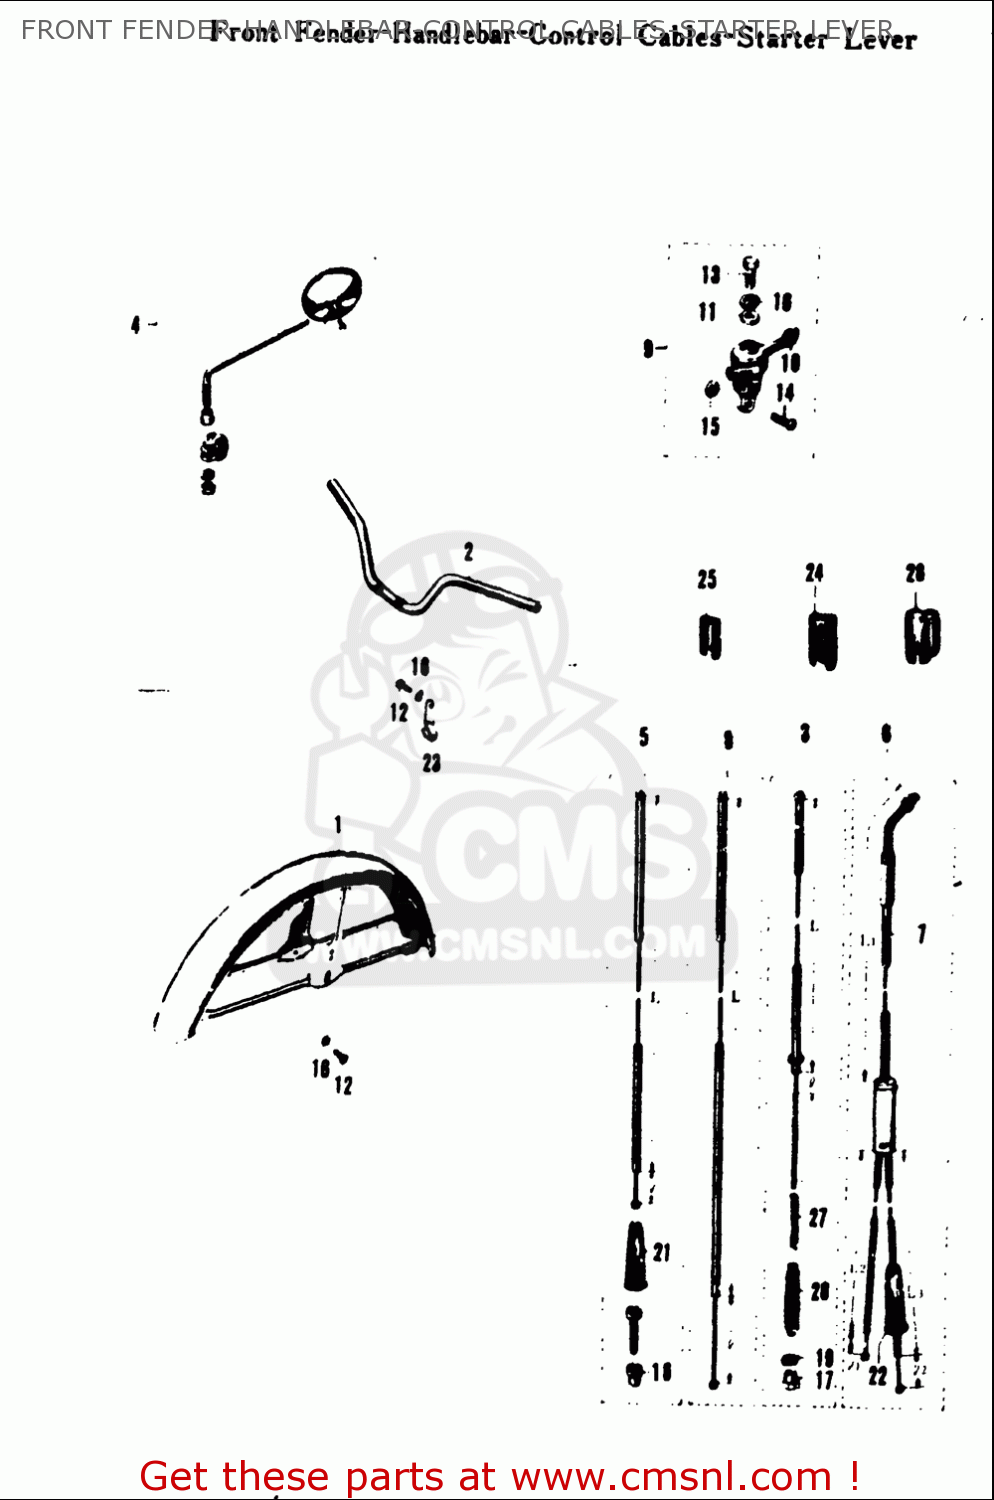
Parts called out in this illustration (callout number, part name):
5	WIRE,CLUTCH
10	LEVER
11	WASHER(6.5X16X1)
14	SCREW
15	NUT
16	WASHER,LOCK
17	NUT
18	NUT
19	BRAKE ROD LEVER
20	SEAL,DUST(7X16X75)
24	CLIP
25	CLIP
